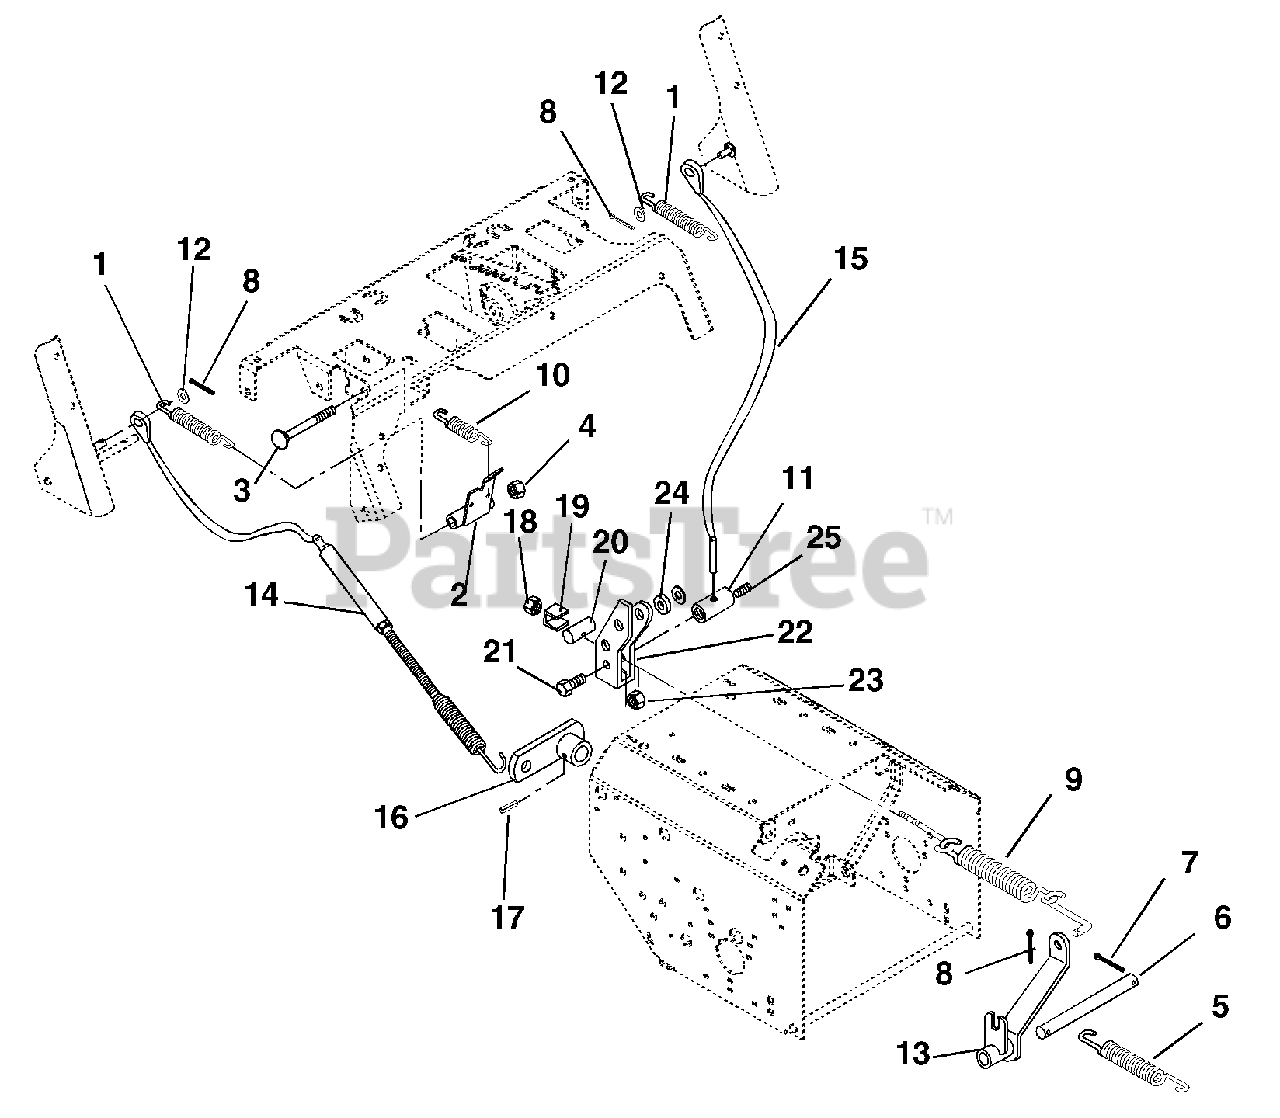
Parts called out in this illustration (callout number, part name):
1	SPRING-EXT .056X.50X3.76
2	ARM, INTERLOCK
3	@BLT-HEX .38-16X3.00 GR5 YWZC
4	@NUT-LK-CTR .38-16 YWZC
5	SG-TENS .080X.73X3.06 WLD 20
6	ROD, FORK PIVOT
7	@PIN-CTR .09X1.00 EXTPRSQCT YZ
8	@PIN-CTR .09X.50 EXTPRSQCT YWZ
9	SPRING ASSEMBLY
10	SPRING-EXT .047X.438X1.45
11	ROD ADAPTER
12	@WSHR-FL-STL.281X.62X.065 YWZC
13	FORK, CLUTCH
14	CABLE, AUGER
15	CABLE, TRACTION
16	LEVER, CLUTCH
17	PIN-ROLL .156X.88
18	@NUT-LK-NYL .312-18 YWZC
19	ADAPTER SPACER
20	ADAPTER
21	@BLT-HEX .31-18X.75 GR5 YWZC
22	CLUTCH ENGAGEMENT YOKE
23	@NUT-LK-CTR .31-18 YWZC
24	SPACER 1.00 X .64 X .38
25	SCR-SET .31-18X.38 SKHCUPDL
